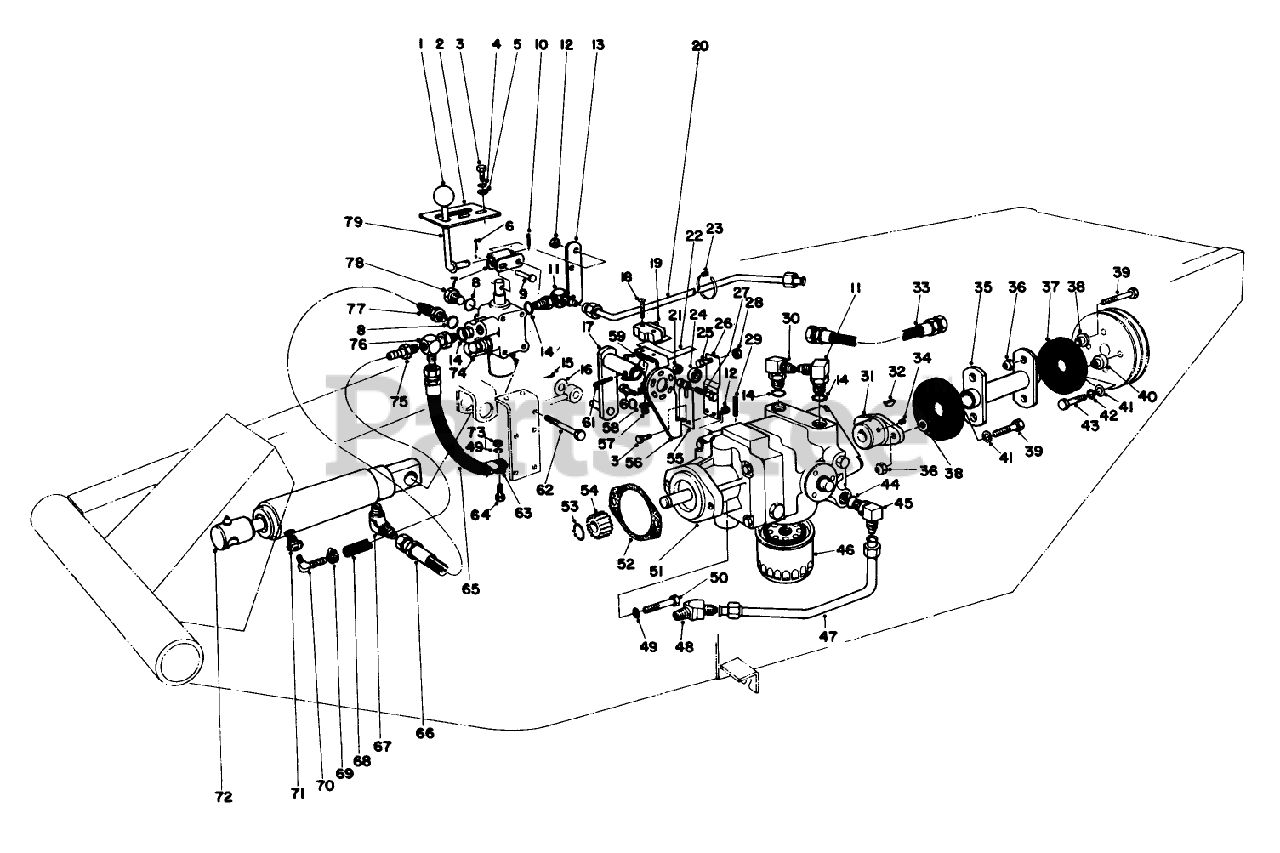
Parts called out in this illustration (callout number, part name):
2	LATCH-LEVER, VALVE
3	SCREW-HH
4	WASHER-LOCK
5	WASHER-FLAT
6	PIN-COTTER
7	Link-Valve Lever
8	O-RING
9	PIN-CLEVIS
10	PIN-ROLL
11	FITTING-ELBOW, 90 DEG
12	NUT-LOCK, NI
13	LEVER-VALVE, PIVOT MOUNT
14	O-RING
15	PIN-COTTER
16	WASHER-FLAT
17	Lever-Pump
18	SCREW-MACHINE
19	Micro Switch
20	PRESSURE LINE TUBE
21	NUT-LOCK, NI
22	STOP-SPRING, LEAF
23	TIE-CABLE
24	BEARING-BALL
25	SCREW-HH
26	EXTENDED LEAF SPRING ASM
27	SCREW-HH
28	NUT-HEX
29	PIN-ROLL, SLOTTED
30	FITTING-HYD, 90 DEG
31	HUB-PUMP
32	KEY-WOODRUFF
33	PUMP-COOLER HOSE
34	SCREW-SET, HSH
35	DRIVE COUPLING WA B
36	NUT-LOCK, CONE
37	COUPLING-RUBBER
38	SPACER-COUPLING
39	SCREW-HH
40	SPACER-COUPLING, RUBBER
41	WASHER-FLAT
42	WASHER-LOCK
43	SCREW-HH
44	O-RING
45	FITTING-ELBOW, 90 DEG
46	FILTER-OIL, TRANSMISSION
47	AXLE-PUMP TUBE ASM
48	45 DEG FITTING
49	WASHER-LOCK
50	SCREW-HH
51	Transmission Inline (Incl. Ref. #32)
52	GASKET
53	Ring-Snap
54	Gear
55	SPRING-LEAF
56	Plate-Pump
57	NUT-HEX
58	WASHER-LOCK, INTERNAL
59	WASHER-LOCK/EXT
60	1/4-20 X 3/4 THDG SCR
61	PIN-SPRING
62	SCREW-HH
63	CLAMP-R
64	SCREW-HH
66	VALVE-CYLINDER HOSE
67	ELBOW
68	GAS LINE
69	CLAMP-HOSE
70	CONNECTOR-HOSE
71	REDUCING BSGH
72	Hydraulic Cylinder
73	NUT-HEX
74	Valve ASM
75	FITTING-STRAIGHT
76	FITTING ASM
77	FITTING-ELBOW, 90
79	Lever Valve
